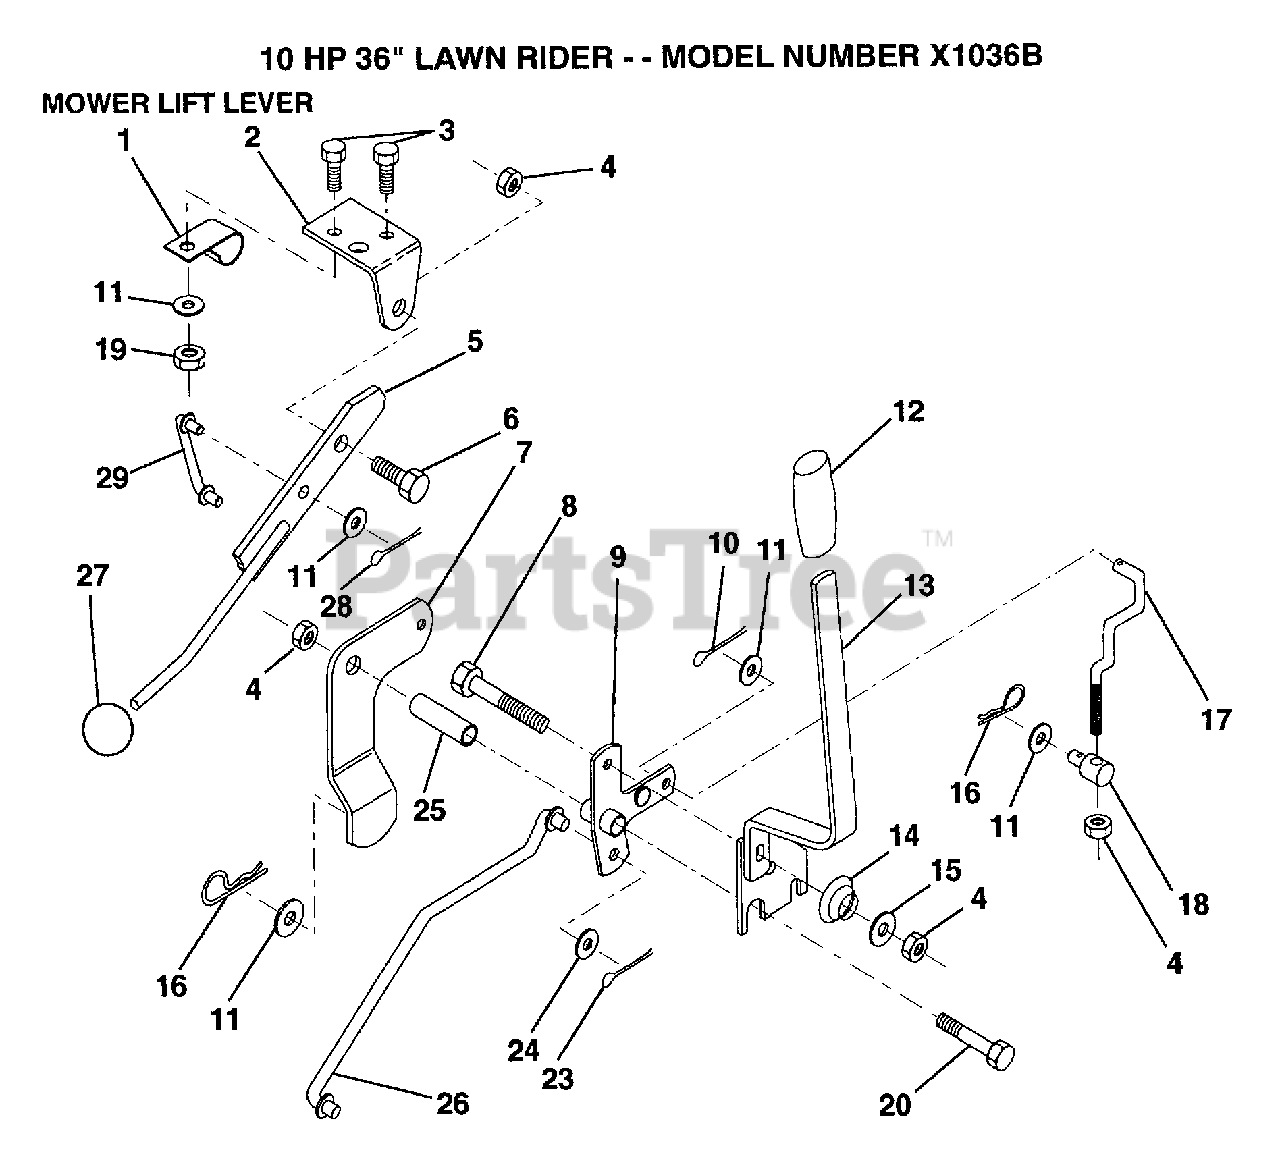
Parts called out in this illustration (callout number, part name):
2	BRKT CLUTCH
3	BOLT
5	CLUTCH LEVER AS
6	"BOLT, SHOULDER LT"
7	MWR CLUTCH ARM AS
8	BOLT
9	"BELLCRANK,LIFT"
10	COTTER PIN
11	WASHER
13	"HDLE,LIFT T"
14	SPRING COMPRESSIO
15	WASHER T
16	SPRING.RETAINER
17	"LINK,LIFT FRT"
18	TRUNION
20	BOLT
23	PIN COTTER 1/8
25	TUBE SPACER
26	"ROD,MOWER LIFT "
27	GRIP HANDLE
29	CLUTCH LINK
